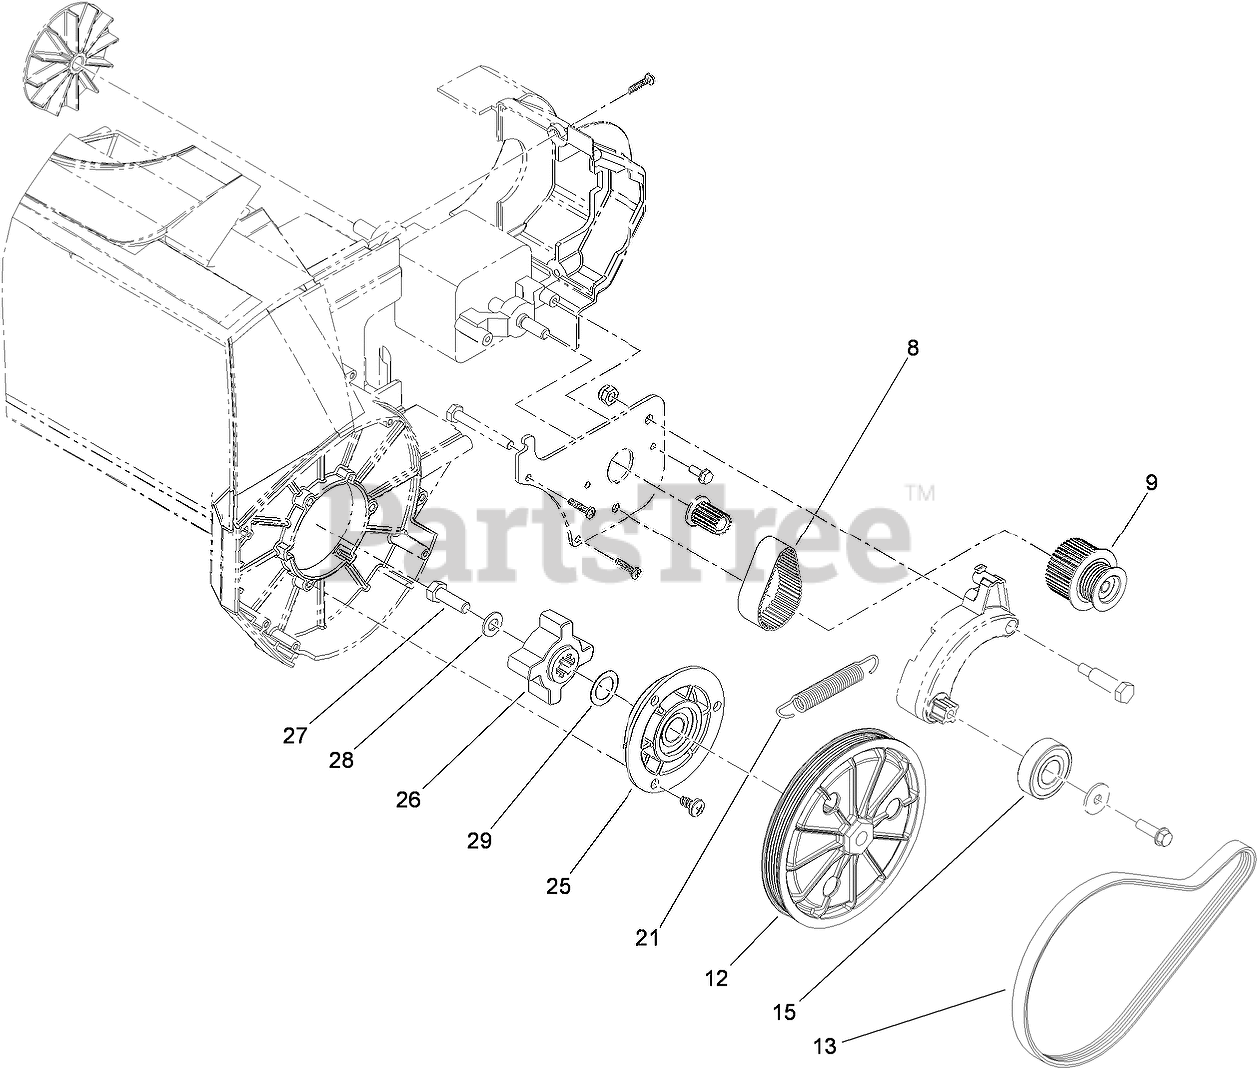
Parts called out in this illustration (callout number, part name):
8	BELT-PULLEY, IDLER/DRIVER
9	IDLER PULLEY ASM
12	PULLEY ASM
13	BELT-DRIVE
15	BEARING-BALL
21	SPRING-IDLER
25	PILLOW BLOCK ASM
26	COUPLER-PULLEY
27	SCREW-HH
28	SPACER
29	WASHER
